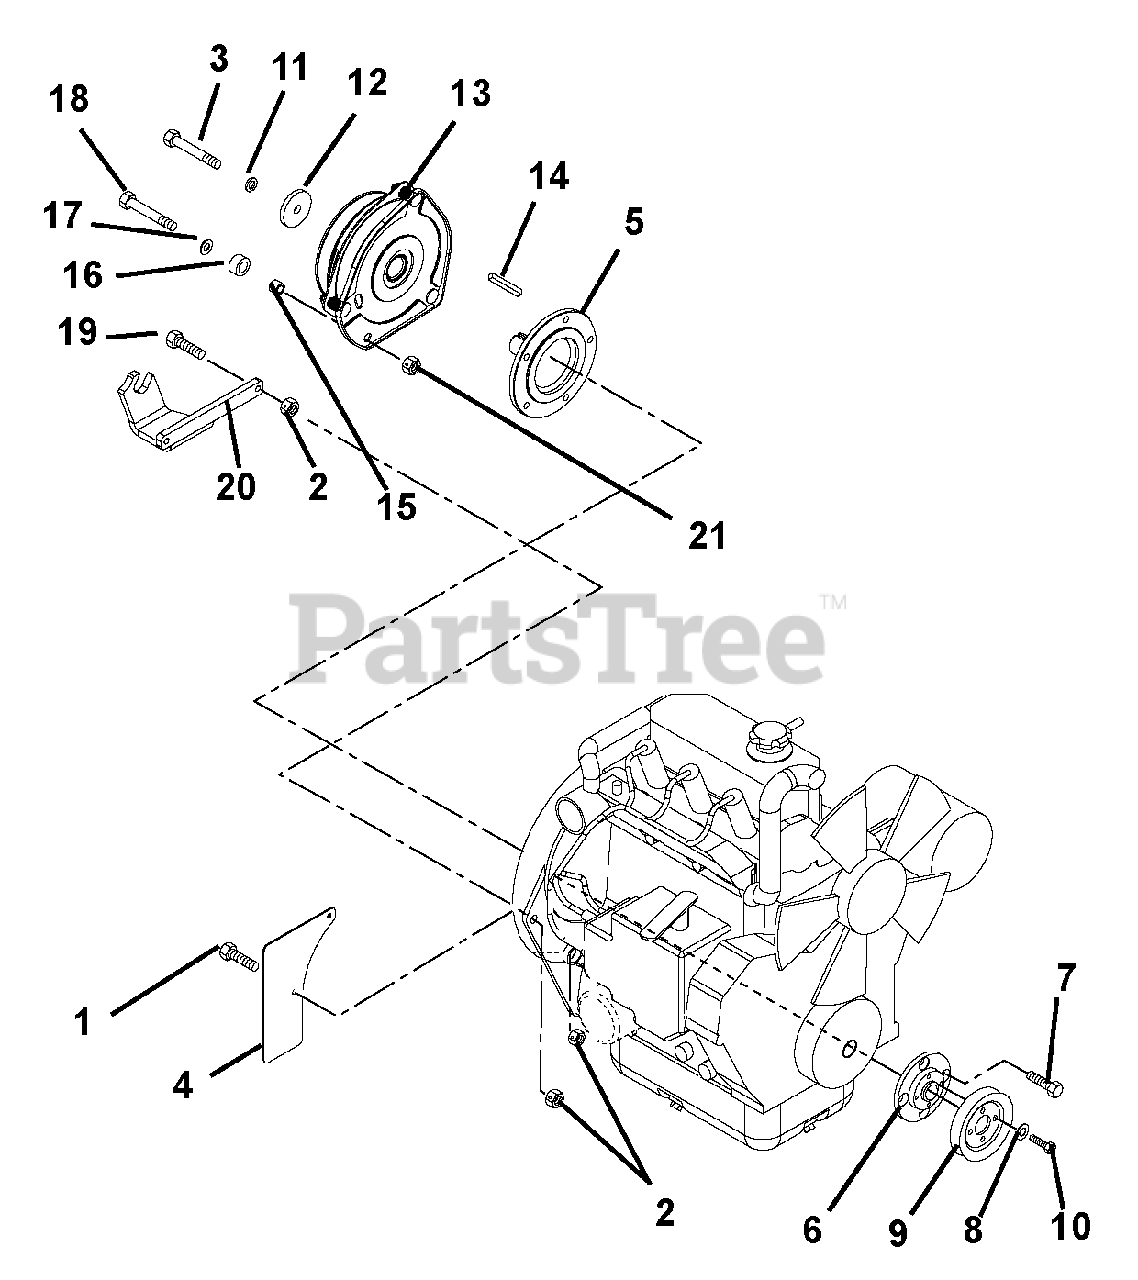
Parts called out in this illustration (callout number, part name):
1	Bolt, Hex .31 -18 x .75 Grade 5
2	Nut, Locking Top Flange .31-18
3	Bolt, Hex .44-20 x 2.50 Grade 5 YZ EP80
4	Guard, Flywheel
5	Stub Shaft
6	Adapter, Sheave
7	Bolt, M8-1.25 x 25
8	Washer, Locking .25 x .062
9	Sheave, Poly-V 1.0 x 3.25
10	Bolt, Hex .25-20 x .75 Grade 5
11	Washer, Locking .44 x .109 Regular
12	Washer, Flat Steel .469 x 2.00 x .25
13	Clutch, Ogura
14	Key .25 x .25 x 2.25
15	Spacer .375 x .686 x .516 Steel
16	Bumper, Rubber .62 x 1.0 x .51
17	Washer, Flat Steel .406 x .812 x .065
18	Bolt, Hex .38-16 x 1.00 Grade 5
19	Bolt, Hex .31-18 x 1.25 Grade 5
20	Bracket, Clutch Stop
21	Nut, Hex Jam .375-16
